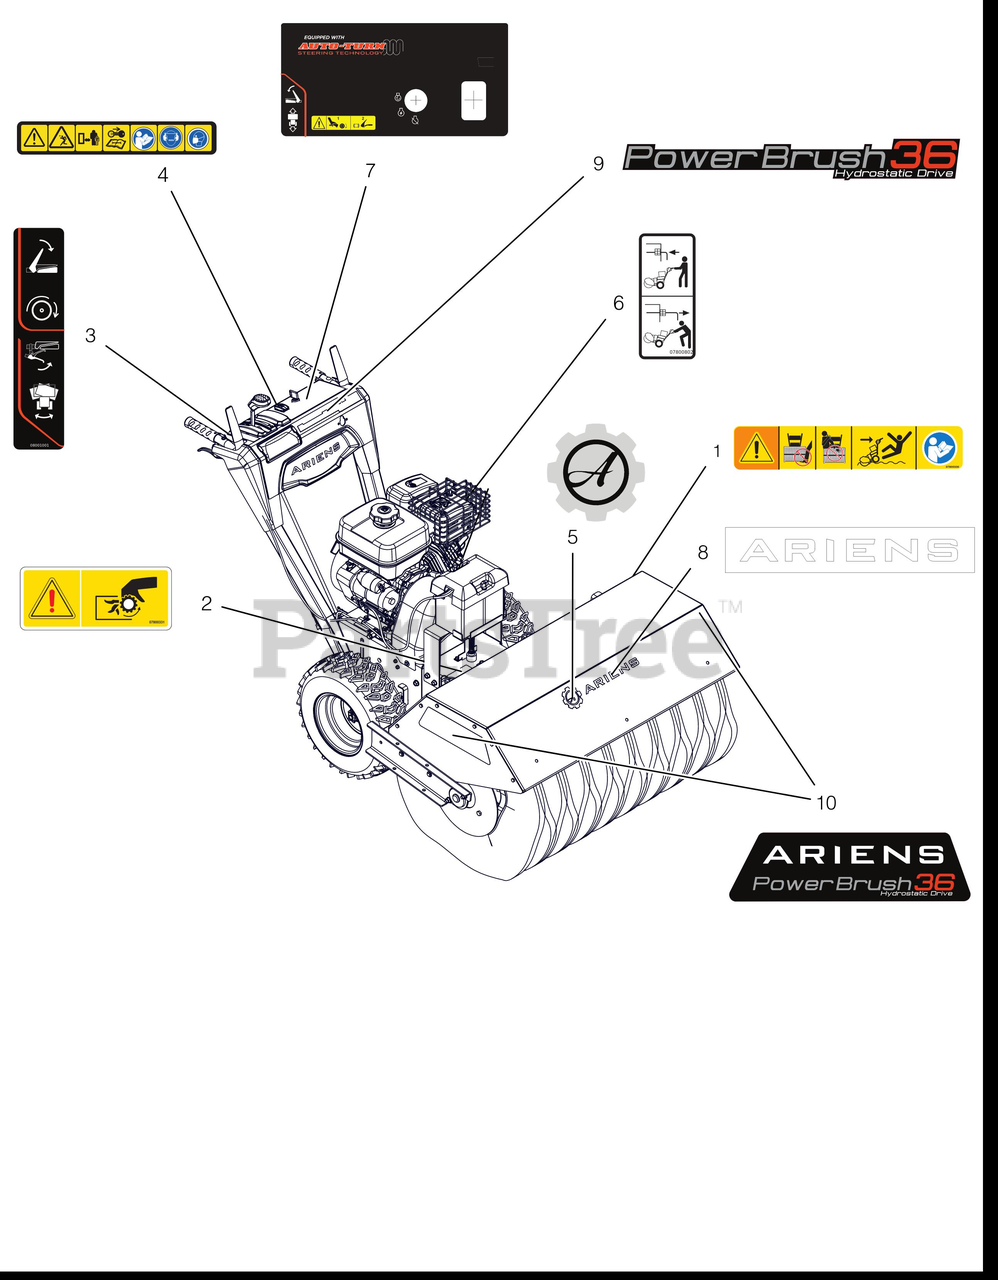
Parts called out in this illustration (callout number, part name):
1	DECAL, DANGER -POWER BRUSH-CE
2	DECAL, PTO WARNING
3	DECAL,CONTROL,BRUSH,RH
4	DECAL, SAFETY, DASH, BRUSH
5	DECAL, ARIENS-GEAR BADGE
6	DECAL, HYDRO BRUSH BYPASS
7	DECAL,CONTROL-12V HYDRO BRUSH
8	DECAL - ARIENS 9.625"
9	DECAL, DASH - PB 36 HYDRO
10	DECAL - ARIENS PB 36 HYDRO
